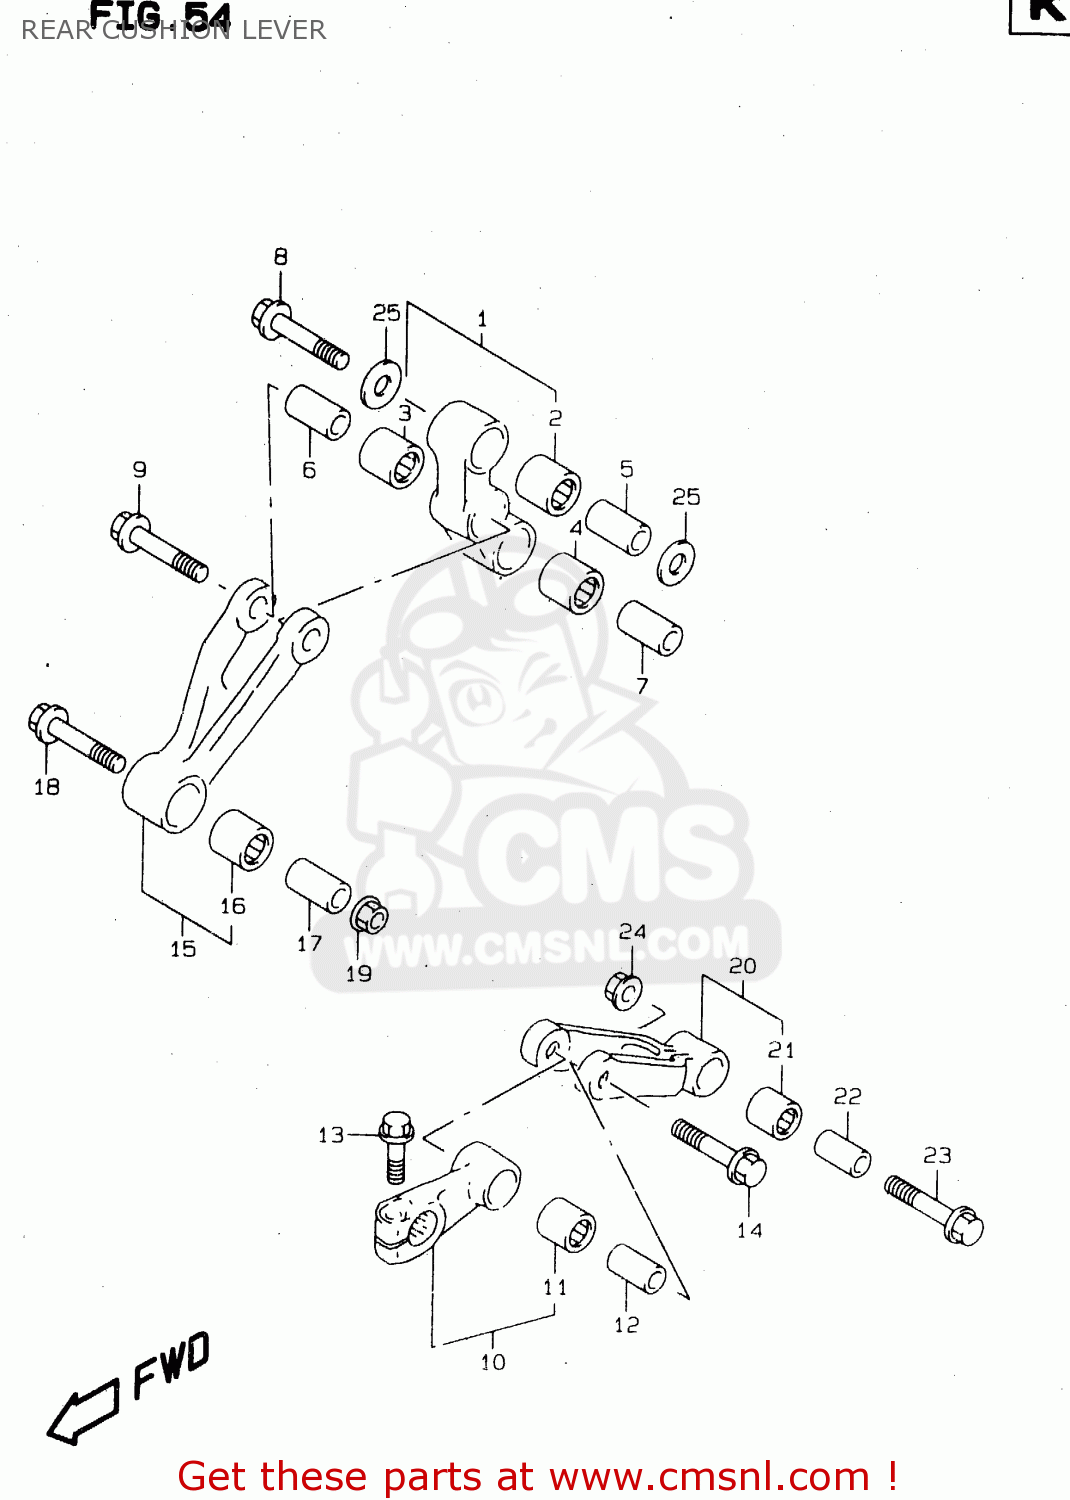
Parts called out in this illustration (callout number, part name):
1	LEVER SET,REAR CUSHION
2	BEARING(20X27X30)
3	BEARING(20X27X32)
4	BEARING(17X24X20)
5	SPACER,RR CUSHION LEVER FR
6	SPACER,RR CUSHION LEVER FR
7	SPACER,RR CUSHION LEVER RR
8	BOLT,RR CUSHION LEVER FR
9	BOLT,CUSHION LEVER FR
10	ARM SET,REAR CUSHION
11	BEARING(14X20X25)
12	SPACER,RR CUSH ARM
13	BOLT(8X31)
14	BOLT,RR CUSHION ROD UPR
15	ROD SET,REAR CUSHION,RIGHT
16	BEARING(20X27X32)
17	SPACER,RR CUSHION LEVER FR
18	BOLT,RR CUSHION LEVER FR
19	NUT 12MM
20	ROD SET,RR CUSHION,L
21	BEARING(14X20X25)
22	SPACER,RR CUSH ARM
23	BOLT,REAR SHOCK ABSORBER
24	NUT
25	SHIM(20X30X0.5)
